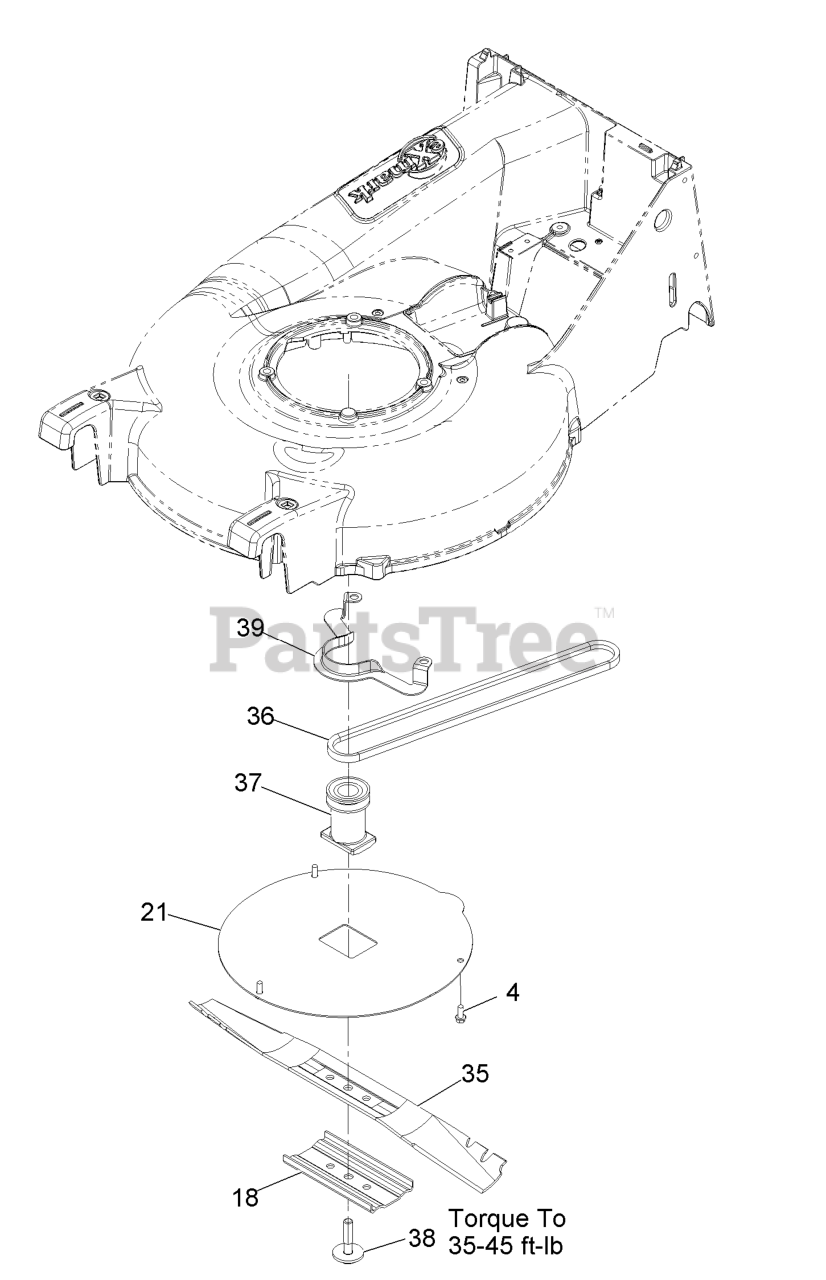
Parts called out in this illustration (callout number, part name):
4	SCREW-HWH
18	SUPPORT-BLADE
36	BELT,3L P21 DRIVE
37	BLADE-ADAPTER
38	BOLT-BLADE, SEM
39	GUIDE-BELT
